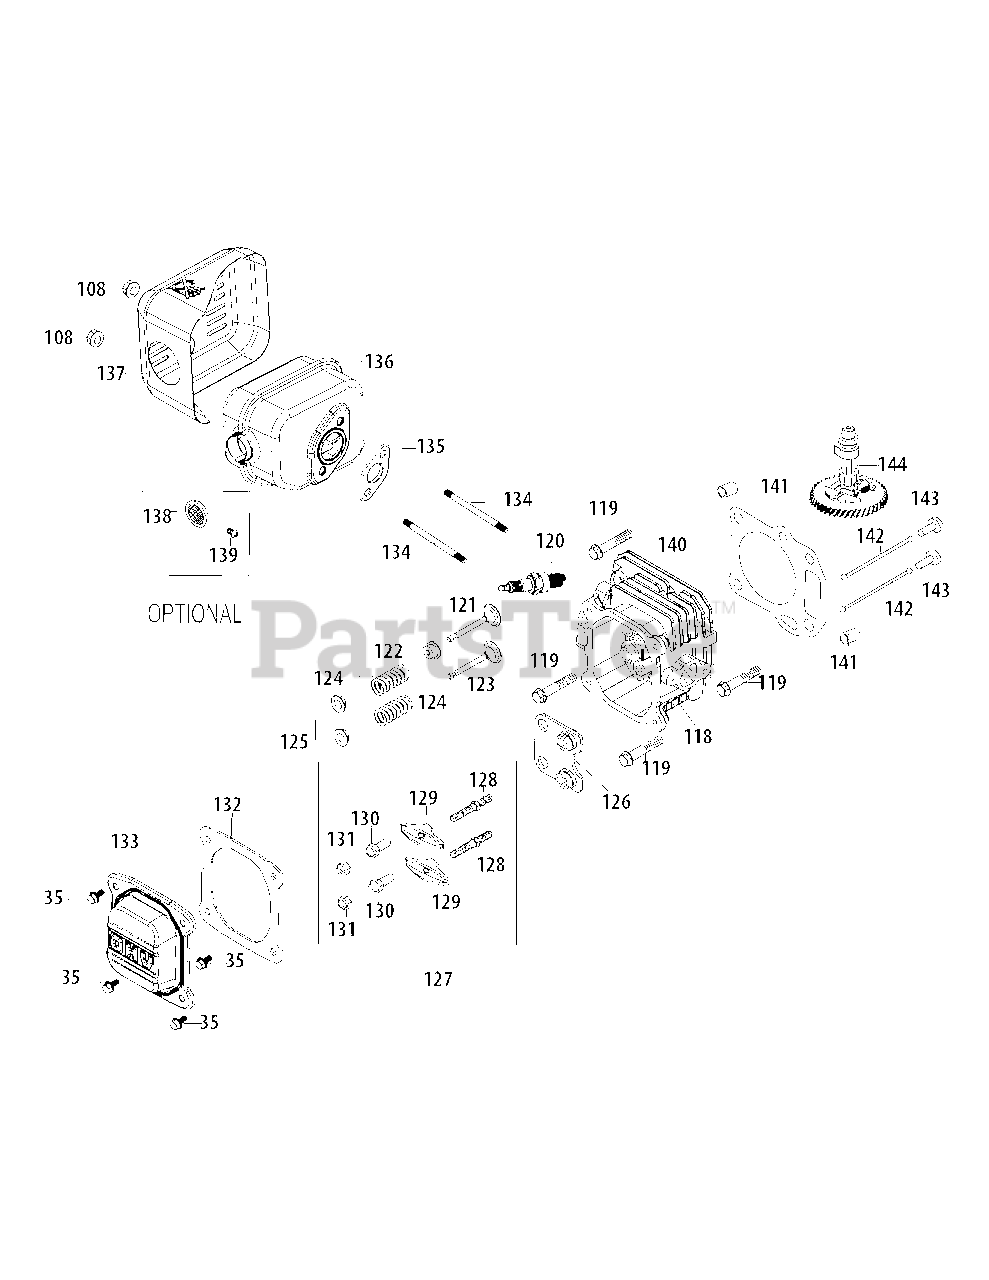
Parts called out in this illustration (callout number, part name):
35	Bolt M6X14 Multi-Purpose
106	Air Filter Cover
118	(Mtd Srvc Kit) Cylinder Head Assy
118	Cylinder Head
119	Bolt M8X54 Cylinder Head
120	Spark Plug/F5Rtc
121	Intake Valve
122	Intake Valve Seal
123	Exhaust Valve
124	Valve Spring
125	Valve Spring Retainer
126	Push Rod Guide
127	Rocker Arm Assembly
128	Rocker Arm Stud
129	Rocker Arm
130	Fulcrum Nut
131	Jam Nut
132	Valve Cover Gasket
133	Valve Cover
134	Muffler Stud M6X95
135	Muffler Gasket
136	Muffler Assembly
137	Muffler Shield
138	Spark Arrestor
139	Spark Arrestor Screw
140	Cylinder Head Gasket
141	Cylinder Head Dowel Pin 010×16
142	Push Rod
143	Tappet
144	Camshaft Assembly
